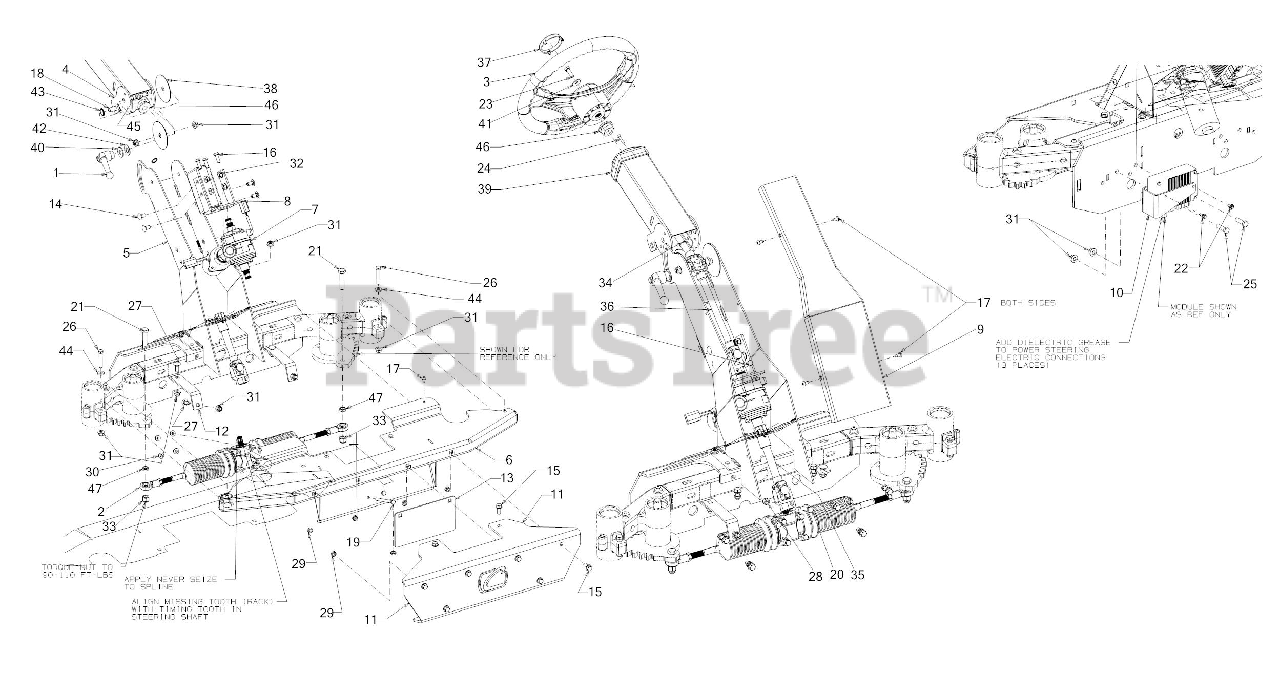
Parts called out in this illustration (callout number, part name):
1	LEVER - ADJ STEERING
2	STEERING GEARBOX
3	STEERING WHEEL
4	UPPER PIVOT COLUMN
5	COLUMN BASE ASSEMBLY
6	FRONT BUMPER ASSEMBLY
7	POWER STEERING ASSEMBLY
8	POWER STEERING MOUNT
9	FRONT COLUMN COVER
10	STEERING MODULE MOUNTING BRACKET
11	FRONT BUMPER UPPER COVER
12	RACK MOUNTING PLATE
13	FRONT BUMPER BACKING PLATE
14	CARRIAGE BOLT 3/8-16 x .750 GR5
15	SCREW 3/8-16 x .875 GR5
16	SCREW M8-1.25 x 25 GR8.8
17	SCREW 1/4-20 x .5
18	CARRIAGE BOLT 1/2-13 x 1.25 GR5
19	SCREW 5/16-18 x 4.00 GR5
20	SCREW 3/8-16 x 1.50 GR8
21	SCREW 1/2-20 x 2.25
22	SCREW M6-1 x .625
23	SCREW 5/16-18 x 1.00 GR5
24	SCREW #10-16 x 1.25
25	SCREW 3/8-16 x 1.25 GR5
26	SCREW 3/8-16 x 2.0 GR5
27	CARRIAGE BOLT 3/8-16 x 1.00 GR5
28	HEX NUT INS L-3/8-16
29	JAM LOCK NUT
30	FLANGE LOCK NUT 5/16-18
32	HEX LOCK NUT
33	HEX NUT 1/2-20 GR8 NYLON
34	RETAINING RING
35	STEERING SHAFT
36	STEERING SHAFT
37	STEERING WHEEL CAP
38	COLUMN PLATE
39	STEERING COLUMN COVER
40	FLAT WASHER
41	BELL WASHER .337 X.867 x .057
42	FLAT WASHER NYLON 5/8
43	LOCK WASHER
44	FLAT WASHER
45	SHOULDER SCREW .498 DIA x .340
46	FLANGE BEARING
